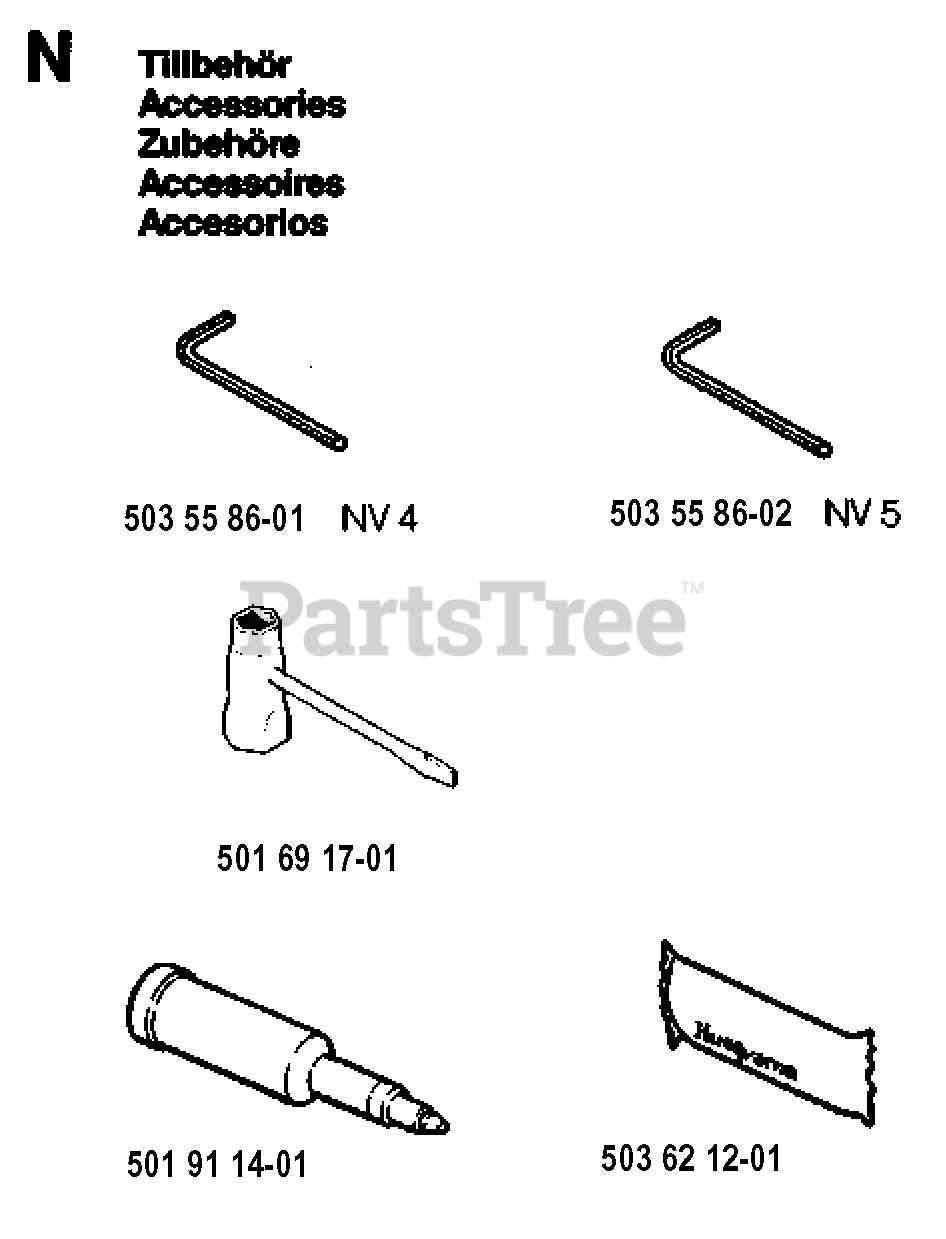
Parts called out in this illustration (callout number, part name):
1	RP TRANSAXLE (K46CR) ETC.PDL
2	SQUARE KEY
15	WASHER
17	SPRING.BRAKE.K46.GREEN
26	SPRING.RETURN.CRUISE
29	ROD.BRAKE.K46
35	ROD.BRAKE.PARKING.GT.H
42	PEDAL COVER T
50	IDLER.FLAT.910.OFFSET
51	NUT LOCK FLG 3/8-16 UNC
52	IDLER.V-GROOVE.910.OFFSET
56	V-BELT.MOWER.92.40.42/K46
64	SHAFT.ASM.PEDAL.BRK.CNTR
70	RP CONSOLE.ASM.PCH.W/TB
73	BOLT HEX 5/16-18 GR 5
74	SCREW.HI-LO.CONSOLE
80	STRAP TORQUE
92	BOLT
99	ROD.SPRING.BYPASS.K46.LT.Z
116	NUT LOCK HEX FLANGE 5/16-18
125	SCREW
153	RETAINER M
159	COTTER PIN
160	RETAINER CLIP
161	SPRING, RETURN LT
163	ROD.CONTROL.PEDAL.K46
166	NUT.PUSH.625
167	LATCH.BRAKE.SPRING
170	KEEPER.V-IDLER.CENTER.
183	SPACER AXLE
184	HANDLE.PARKG.BRK.HUSQ X667
186	SPACER.RETAINER
187	WASHER 12/32X2X10GA
188	RP.LINK.CLUTCH.GROUND.DRIVE
189	BELLCRANK.GROUND.DRIVE.TEX.
190	KEEPER.BELLCRANK.DRIVE
196	SCREW 3/8-16X1
197	LINK.CLUTCH.ANIT-ROTAT
206	BRKT.MOUNT.LATCH.CRUIS
207	LATCH.CONTROL.CRUISE
208	GEAR.SECTOR.CONTROL.CR
209	ROD.CONTROL.CRUISE.GT.
210	ROCKER.ASM.PEDAL.CONTR
211	BEARING.NYLON
213	KNOB.CONTROL.CRUSIE.HU
214	PEDAL.FORWARD.HUSQVARNA.DEALER
215	PEDAL.REVERSE.TEX.GT.4
220	REFLECTOR.RH.TEX GT
221	RETAINER.SPRING.CLIP.H
222	WASHER 21/32 X 1-1/4 X 10 GA.
225	KEEPER.BELT.TRANSAXLE.K46
226	BRACKET.MOUNT.TORQUE.K46.TLT
230	WASHER.HARDENED
284	NUT.U-CHNL.1/4-20.550DP.350PNL
285	SCREW.PHD.1/4-20.BOX DRVE
